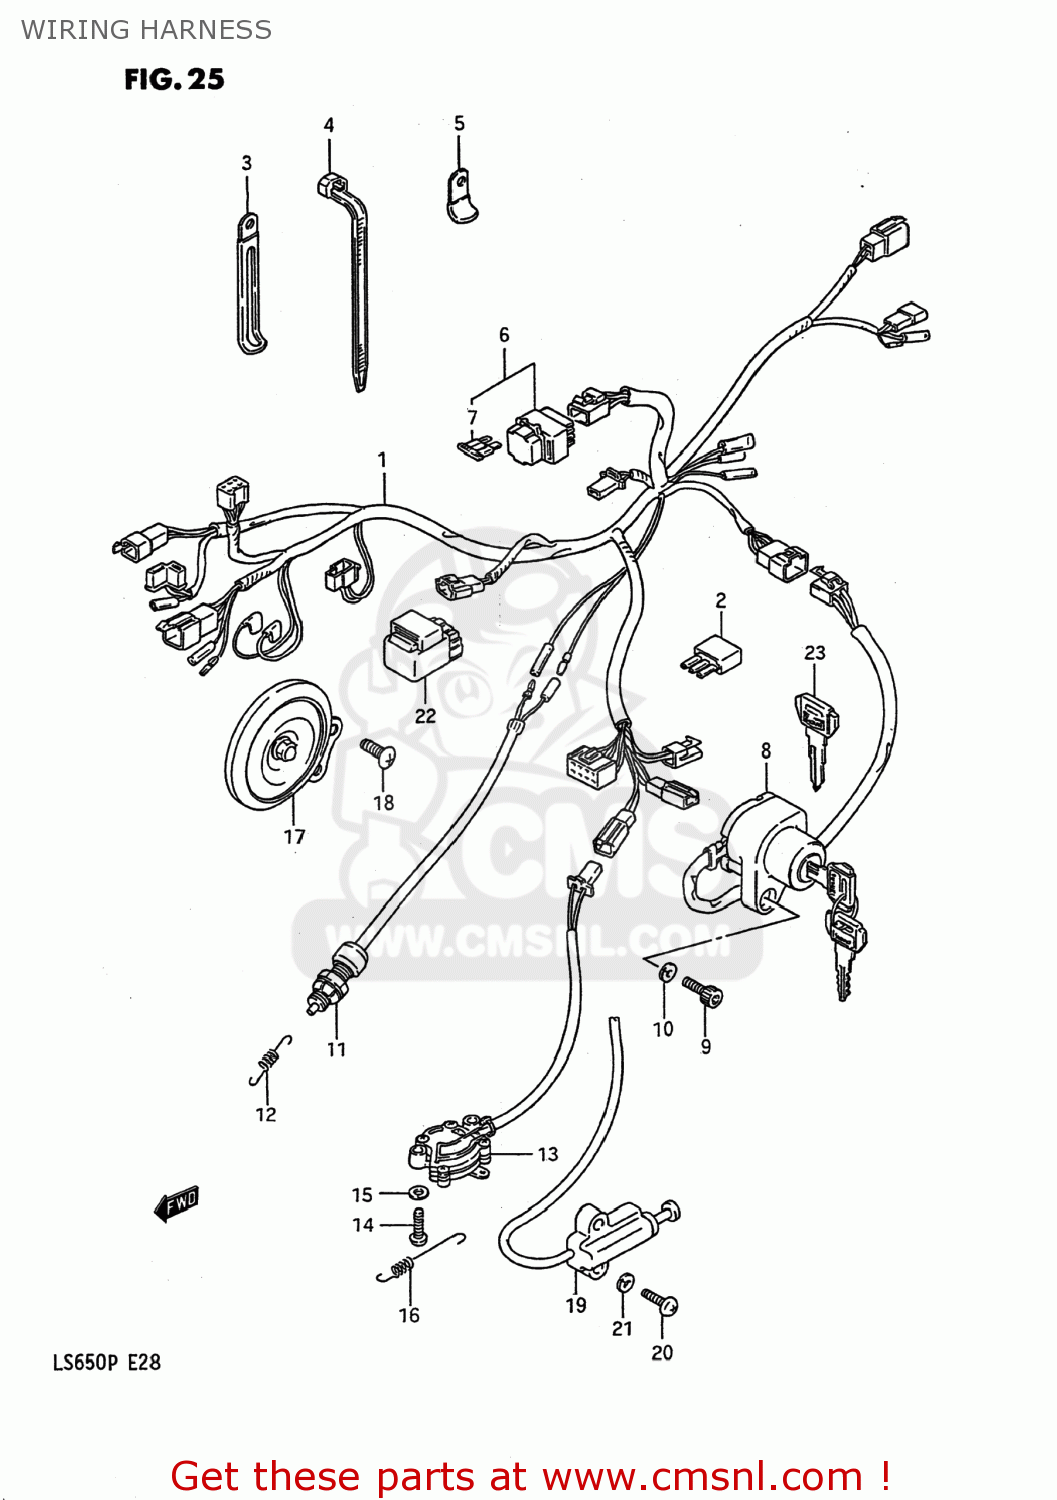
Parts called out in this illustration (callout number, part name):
1	HARNESS,WIRING
2	DIODE(STANLEY DE8804)
3	CLAMP
4	CLAMP(L:125)
5	CLAMP
6	BOX ASSY,FUSE
7	FUSE(20A)
8	SWITCH ASSEMBLY,IGNITION
9	BOLT
10	LOCK WASHER
11	SWITCH ASSY,STOP LAMP
12	SPRING
13	SWITCH ASSEMBLY,SIDE STAND
14	SCREW 5X20
15	WASHER,LOCK
16	SPRING
17	HORN ASSY
18	SCREW 6X12
19	SWITCH ASSEMBLY,SIDE STAND
20	SCREW
21	WASHER,LOCK
22	RELAY ASSEMBLY
23	KEY,BLANK(TYPE:C)
